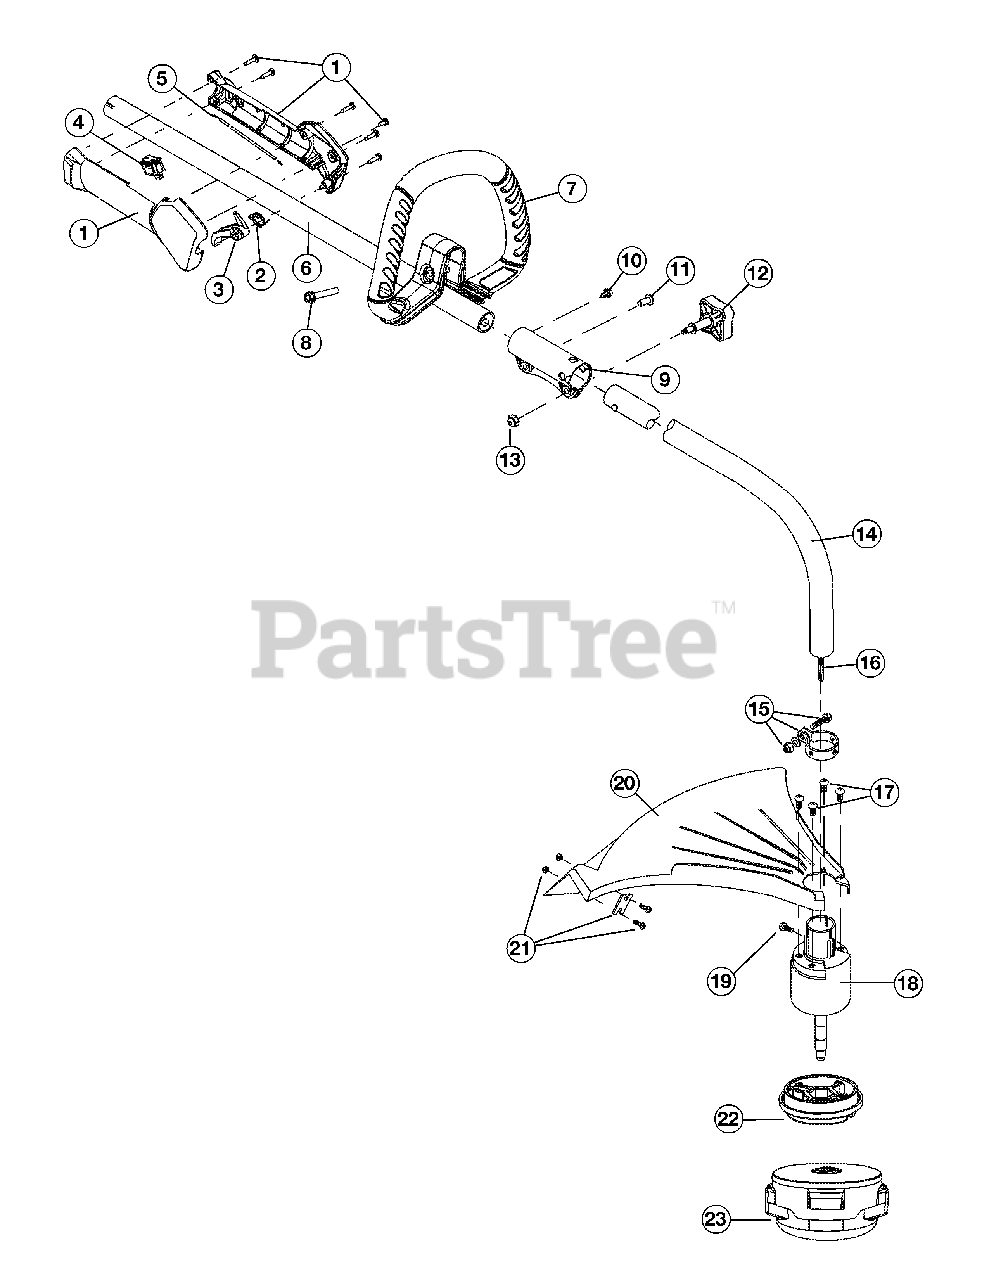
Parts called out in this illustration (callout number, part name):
1	Throttle Housing Assembly
2	Throttle Trigger Spring
3	Throttle Trigger
5	Throttle Cable Assembly
6	Upper Drive Shaft Housing Assembly
7	D-Handle Assembly
9	Split boom Coupler
12	Adjustment Knob
13	Knob Retaining Nut
14	Lower Drive Shaft Housing Assembly
15	Lower Clamp Assembly
16	Lower Flexible Drive Shaft
17	Shield Mounting Screw
18	Bushing Housing Assembly
19	Anti-Rotation Screw
20	Shield Assembly
21	Blade Assembly
23	Spool Assembly
